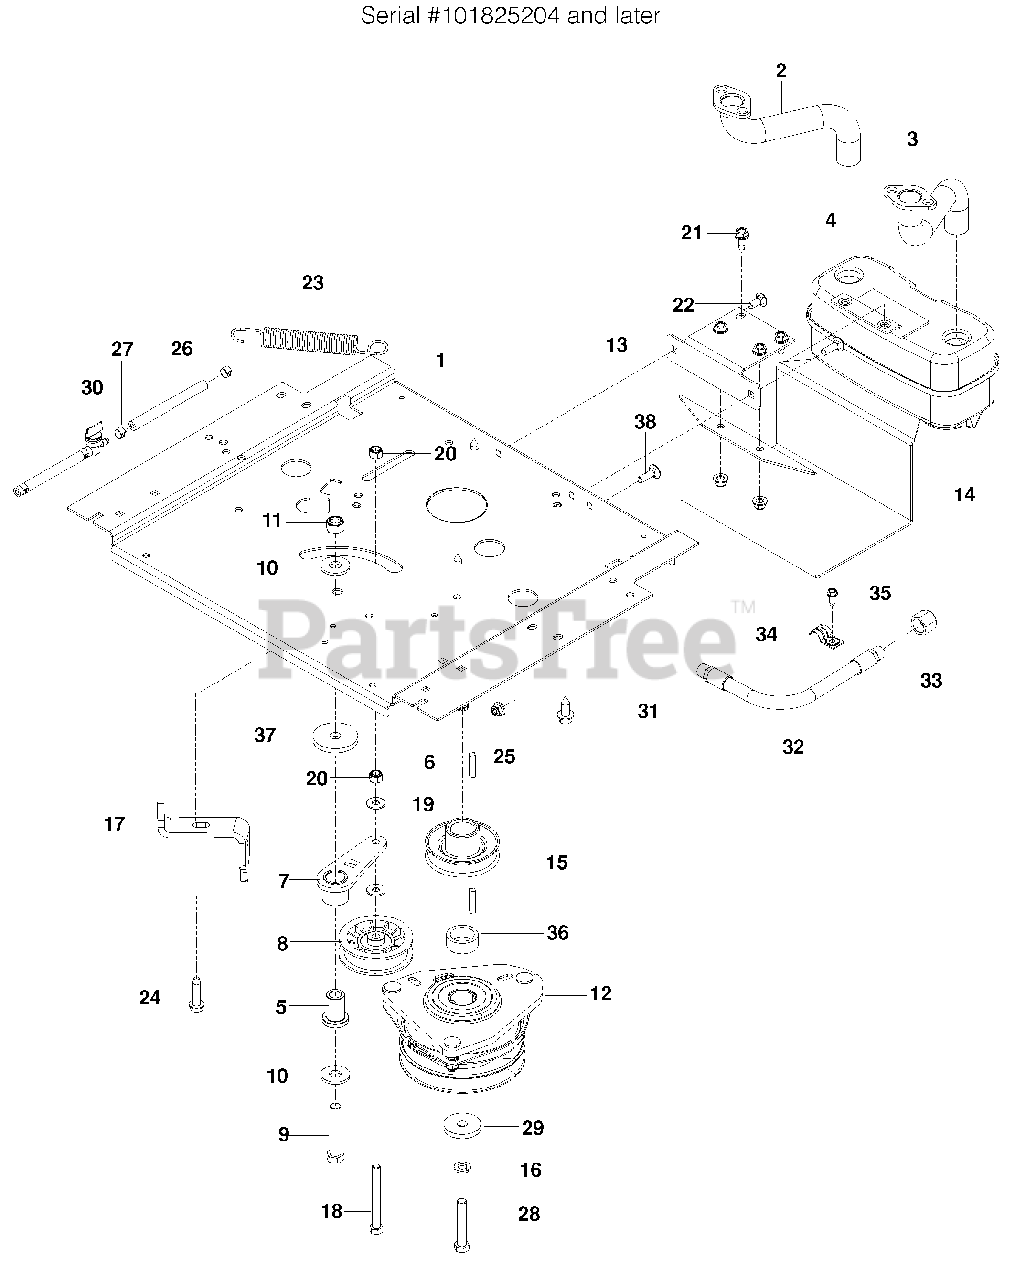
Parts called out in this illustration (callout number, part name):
1	PLATE, ENGINE BLK
2	EXHAUST TUBE, RT
3	EXHAUST TUBE, LT
4	MUFFLER ASM TWIN
5	PIVOT, IDLER
6	KEY 1/4 SQ x 1 1/4
7	ARM, IDLER
8	PULLEY, IDLER
9	HCS 1/2 -13 x 3 3/4
10	WASHER 1/2 FLAT
11	NUT 1/2 HEX NYLOC
13	BRACKET, MUFFLER BLK
14	GUARD, MUFFLER BLK
15	PULLEY, ENGINE
16	WASHER 7/16 SLW
17	STOP, CLUTCH BLK
18	HCS 3/8-16 x 3 1/2 TPBLT
19	WASHER 5/16 STD FLAT
20	NUT 3/8-16 HEX NYLOC
21	BOLT 5/16-18 x 3/4 THD FRM
22	RHSNB 5/16-18 x 3/4
23	SPRING, DECK DRIVE
24	BOLT 3/8-16 x 11/2 THD FRM
25	NUT 5/16-18 FLANGE NYLOC
26	FUEL LINE 5"
27	CLAMP, HOSE
28	HCS 7/16-20 x 2 1/2
29	WASHER, CLUTCH
30	VALVE, FUEL
31	HHFS 3/8-16 x 1 THD FRM
32	HOSE, DRAIN
35	SCREW 1/4 -20 x 5/8 SLF TAP
37	WASHER, HEAVY
38	RHSNB 5/16-18 x 1
